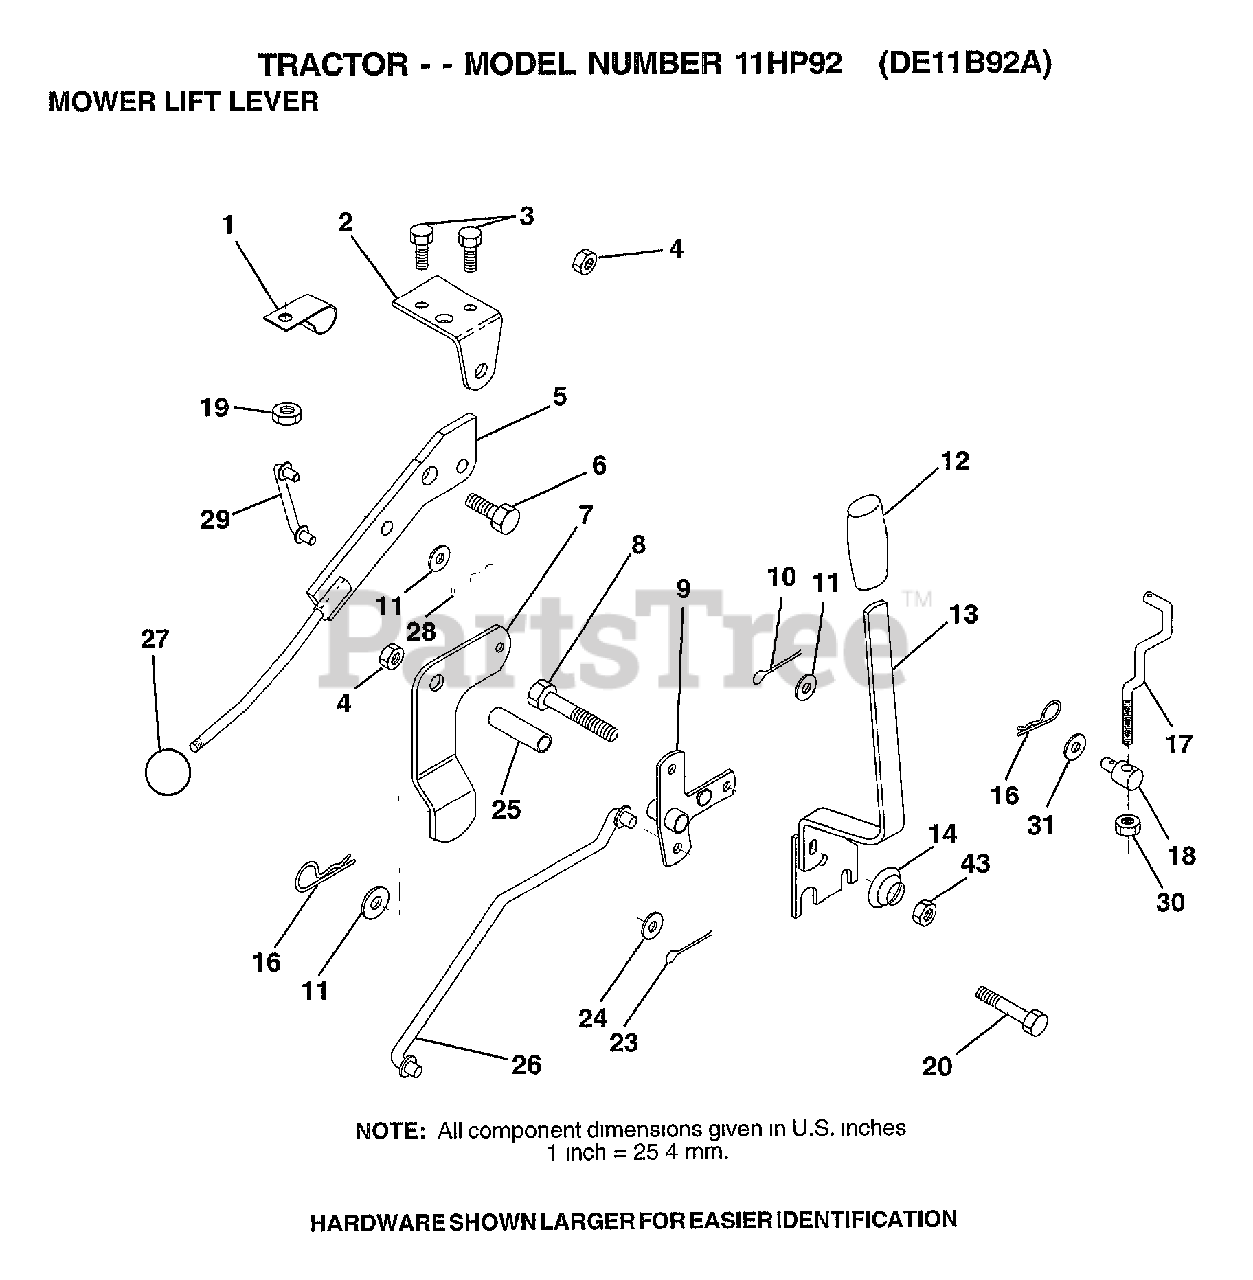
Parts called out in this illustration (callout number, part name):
1	"CLIP,INSULATOR"
2	BRKT CLUTCH
3	BOLT HXHD FIN
5	LEVER.ASM.CLUTCH
6	"BOLT, SHOULDER LT"
7	MWR CLUTCH ARM AS
8	BOLT
9	"BELLCRANK,LIFT"
10	COTTER PIN
11	WASHER
13	HANDLE.ASM.LIFT
14	SPRING COMPRESSIO
16	SPRING.RETAINER
17	"LINK,LIFT FRT"
18	TRUNION ADJ
20	BOLT
23	PIN COTTER 1/8
25	TUBE SPACER
26	ROD LIFT MOWER
27	KNOB T(3/8 HOLE)
28	RETAINER M
29	CLUTCH LINK
30	NUT
31	WASHER
